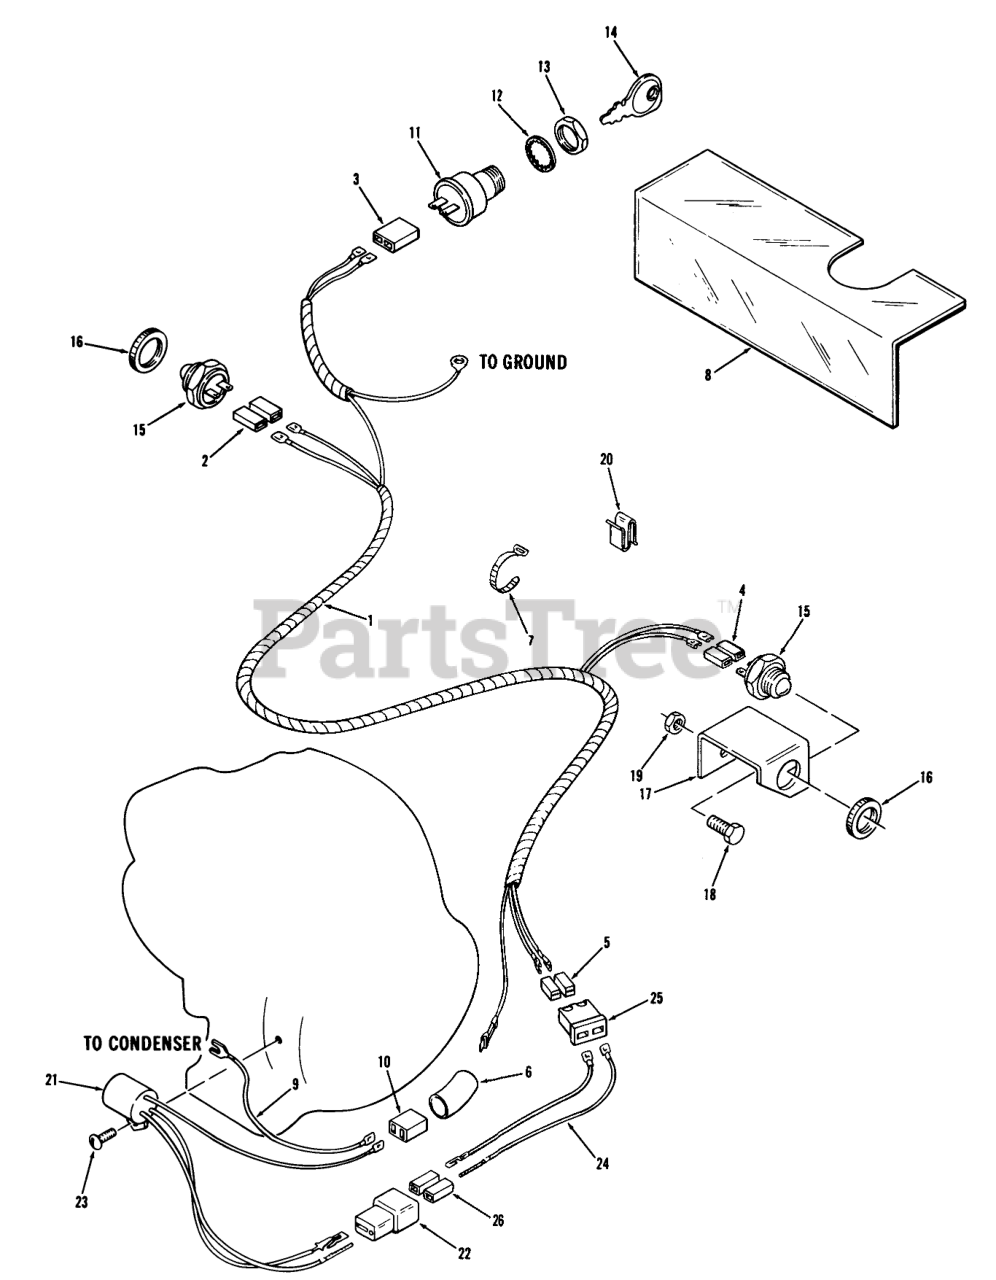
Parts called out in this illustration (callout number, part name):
1	Wiring Harness
2	Connector Housing Int Sw
3	Conn. Body-Part of 2
4	Connector Housing Int Sw
5	Connector Housing F
6	Rubber Sleeve
7	PLASTIC TIE
8	CONTROL PROTECTOR
9	Assy-Wire
10	Rubber Sleeve
11	SWITCH
12	LOCKWASHER
14	KEY SWITCH
15	SWITCH-INTERLOK CLUT
16	NUT-SPECIAL 9/16-18
17	Bracket
18	BOLT
19	Nut
20	CLIP-WIRE
21	MODULE-INTERLOCK
22	Conn. Body-Part of 15
23	Screw
24	Wire Assy
25	Connector Housing M
26	Connector Body
